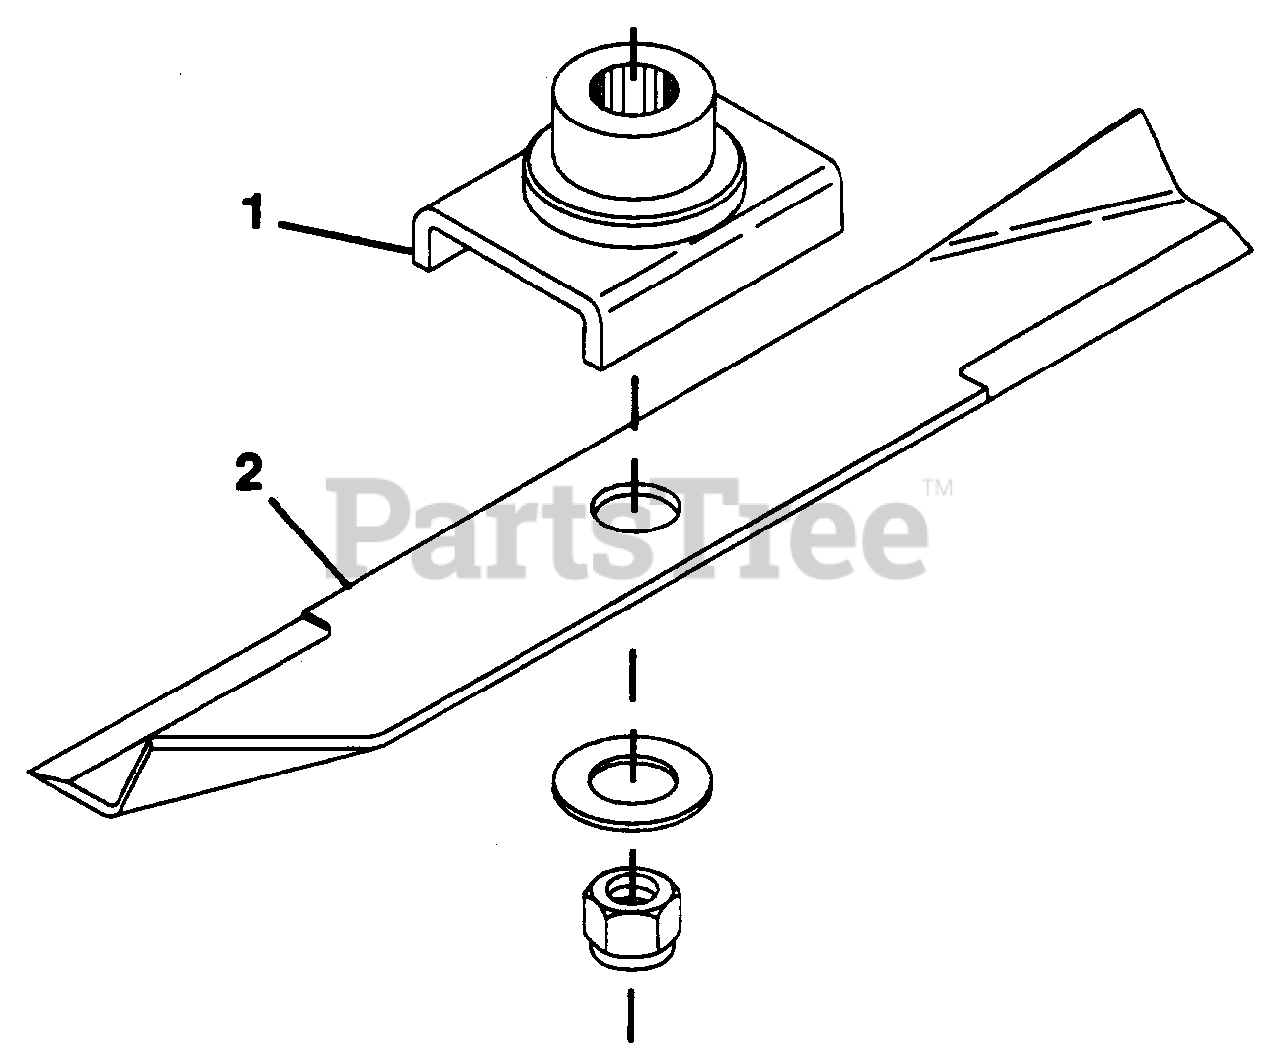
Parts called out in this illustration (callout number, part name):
1	Weldment, Blade Cradle
2	Blade, 50" Mower
2	Blade, 60" Mower
2	Blade, 72" Mower
